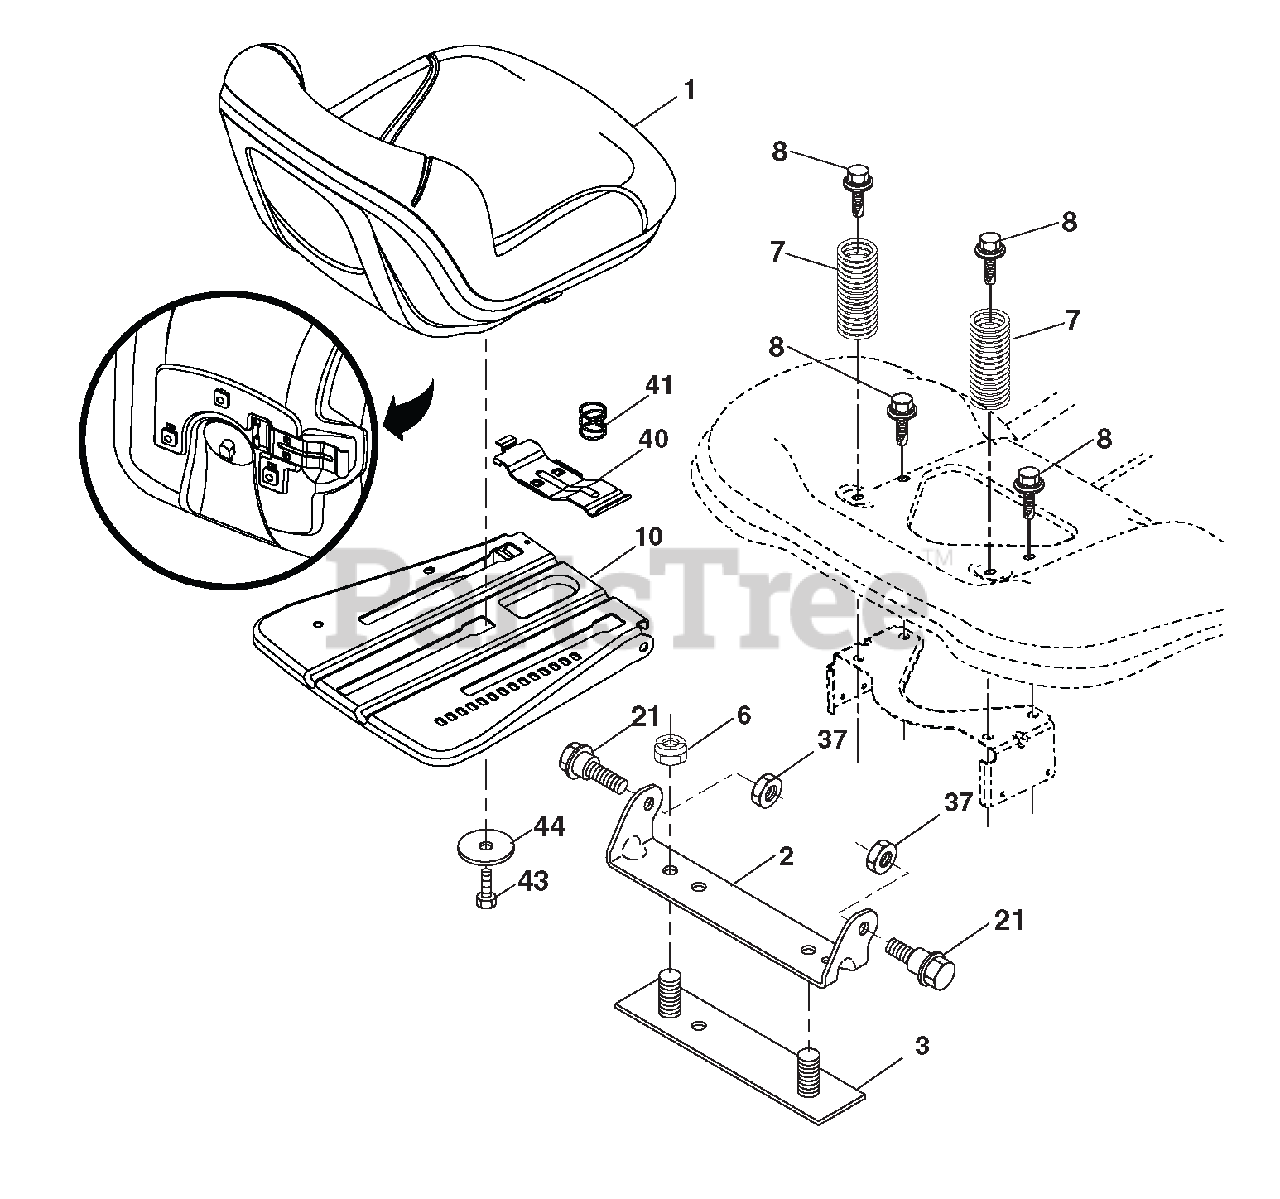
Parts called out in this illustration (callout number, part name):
1	SEAT.TA150.KB/SLD.BLK.ARIENS
2	BRACKET.PIVOT.FENDER.2002
3	STRAP ASM.FENDER.94
6	Locknut, Washer Insert 3/8-16
7	SPRING.SEAT.CPRSN.2.250.BLK.ZI
8	BOLT.5/16-18UNCX3/4 W/SEMS.BLK
10	PAN ASM.SEAT.3PT.
21	BOLT.SHLD.5/16-18 UNC-2A.BLK D
37	Locknut, Washer Insert 5/16-18
40	HANDLE.SLIDE.SEAT.TEX.MILSCO
41	SPRING.LATCH.SEAT.TEX
43	BOLT.FIN.HEX.3/8-16UNC X 3/4
44	WASHER.13/32 X 2 3/8 X 12GA.
